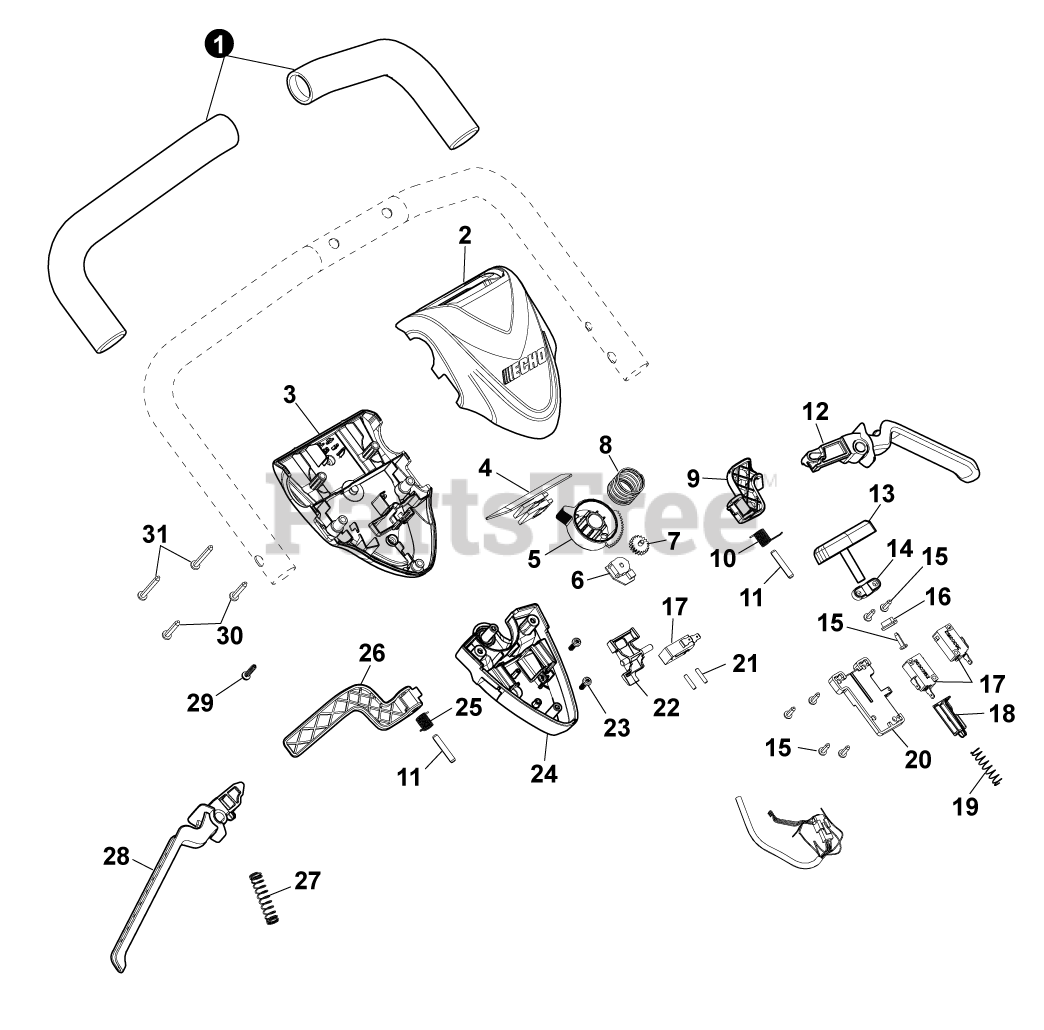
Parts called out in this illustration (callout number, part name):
1	GRIP, HANDLE
2	COVER, TOP SWITCHBOX
3	COVER, LOWER SWITCHBOX
4	SWITCH, MEMBRANE
6	POTENTIOMETER
7	GEAR, SPEED ADJUSTMENT
9	TRIGGER, LEFT SPEED
11	PIN, LOCATING
12	TRIGGER, LEFT
13	BUTTON, SWITCH
14	PLATE, RETAINING
20	PLATE, RETAINING
21	SHAFT, PIN
22	PLATE, RETAINING
24	COVER, SPEED
26	TRIGGER, RIGHT SPEED
28	TRIGGER, RIGHT
